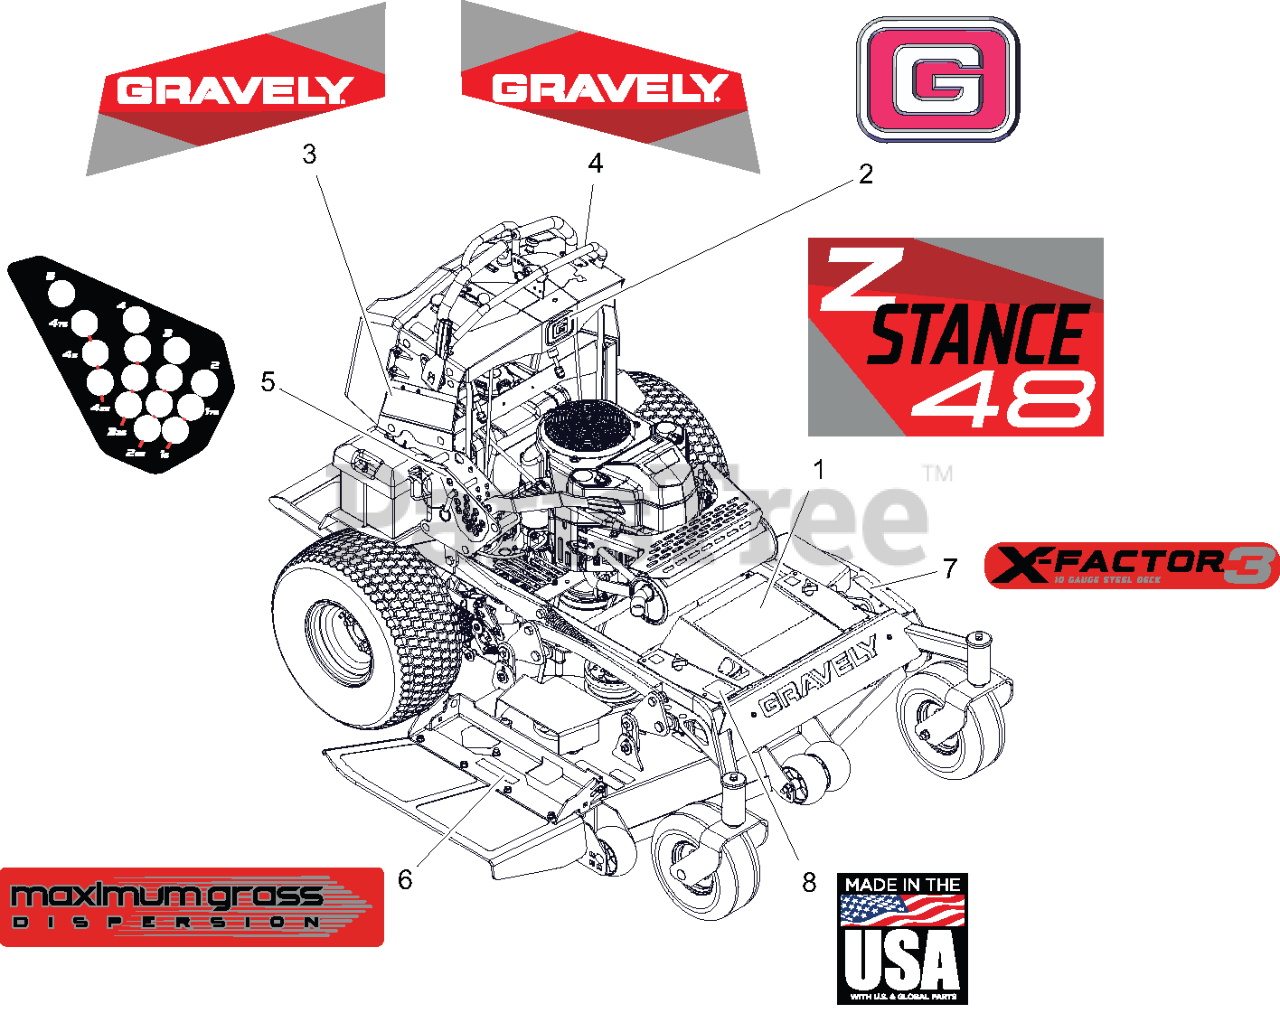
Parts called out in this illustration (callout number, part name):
1	DECAL- Z-STANCE 48"
2	DECAL, GRAVELY BRAND
3	DECAL,RH GRAVELY LOGO
4	DECAL- LH GRAVLEY LOGO
5	DECAL- DECK - HEIGHT ADJUST
6	DECAL, DECK - MAX GRASS
7	DECAL, X-FACTOR 3
8	DECAL, MADE IN USA
